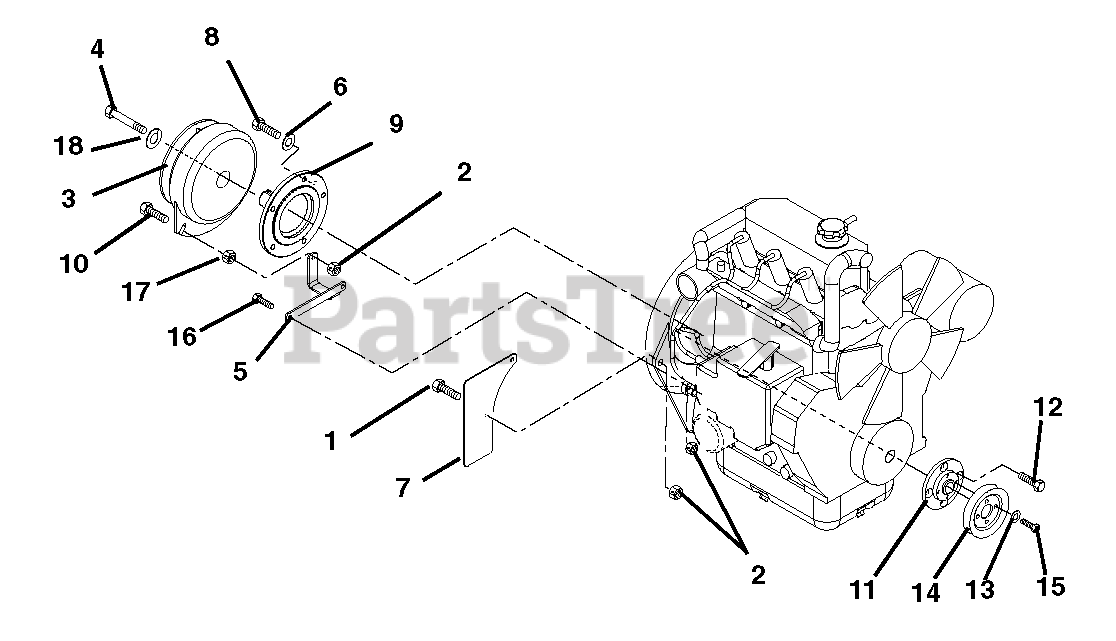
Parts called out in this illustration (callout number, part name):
1	Bolt, Hex .31 -18 x .75 Grade 5
2	Nut, Locking Top Flange .31-18
3	Clutch, Warner
4	Bolt, Hex .44-20 x 2.50 Grade 5 YZ EP80
5	Stabilizer, Clutch
6	Washer, Lock .31 x .078 Regular
7	Guard, Flywheel
8	Bolt, Hex M8 x 1.25 x 25 Grade 8
9	Stub Shaft
10	Bolt, Hex .31-18 x 1.50 Grade 5
11	Adapter, Sheave
12	Bolt, M8-1.25 x 25
13	Washer, Locking .25 x .062
14	Sheave, Poly-V 1.0 x 3.25
15	Bolt, Hex .25-20 x .75 Grade 5
16	Bolt, Hex .31-18 x 1.00 Grad 5
17	Nut, Hex .31-18
18	Washer, Locking .44 x .109 Regular
NS	Kit, Break Pole Module Replacement
